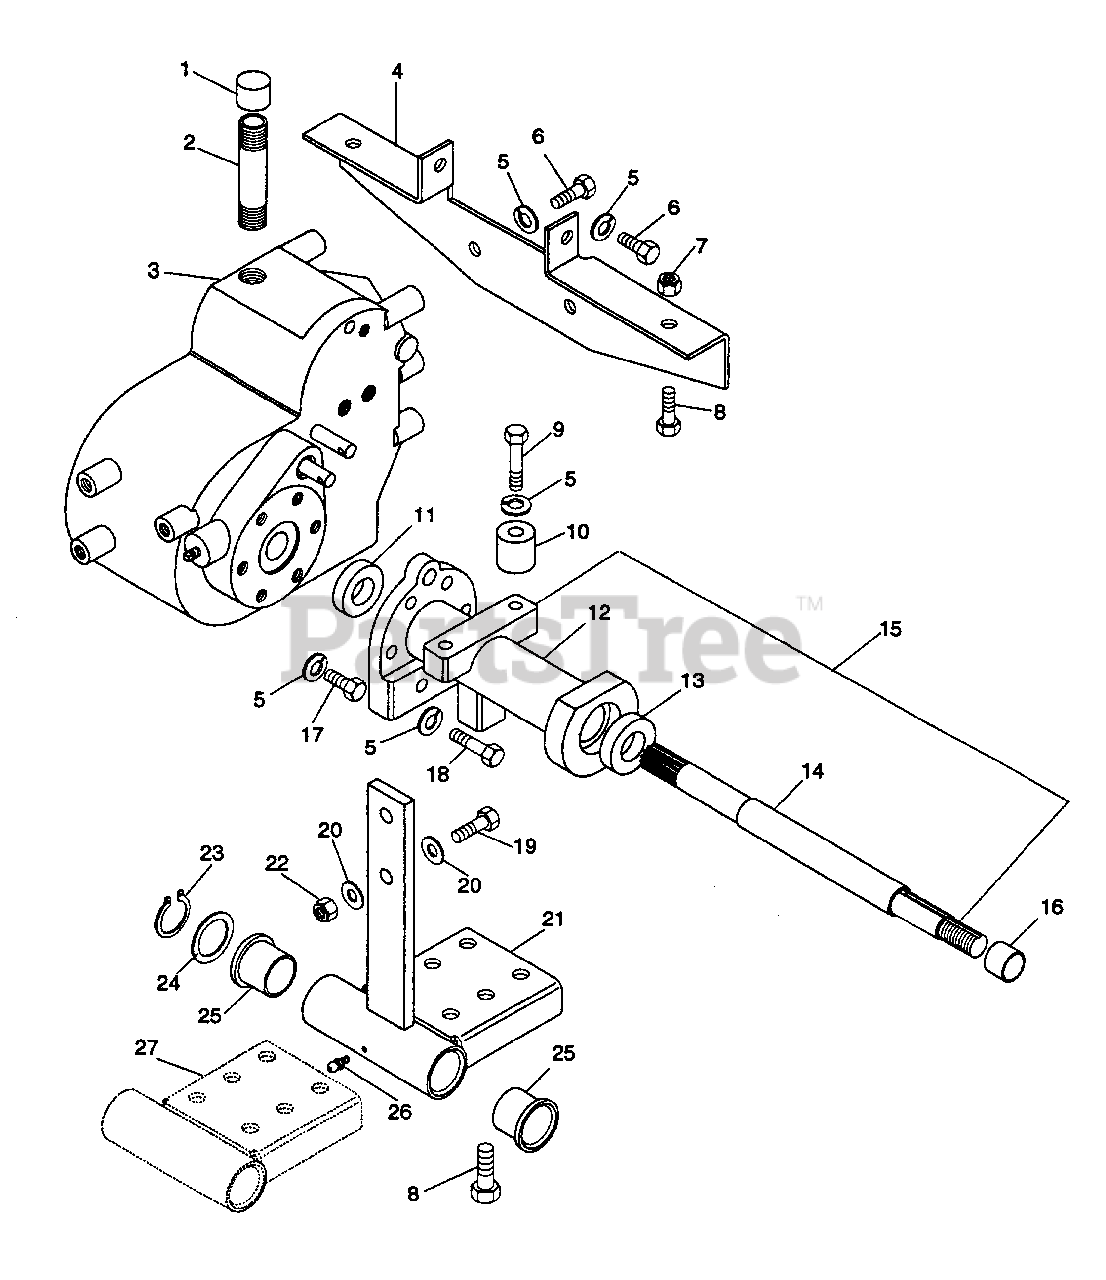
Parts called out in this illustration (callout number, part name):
1	CAP, PIPE .75 UNFIN MAL LR
2	NIPPLE, PIPE .75 X 5.0 UNFIN STL
3	TRANSAXLE
4	PLT, TRANSAXLE
5	WSHR-LOCK .50 REG.
6	BLT-HEX .50-13 X 1.25 PL GR 5
7	NUT-LK-NYL .625-11 PL
8	BLT-HEX .625-11 X 1.50
9	BLT-HEX .50-13 X 2.75 PL GR 5
10	SPCR, FRAME
11	RING, ALIGNMENT
12	HOUSING, AXLE
13	BRG, BALL 1.18 X 2.440 X .629
14	AXLE
15	ASM, AXLE HOUSING
16	SPCR, AXLE 1.75 X .800 ST
17	BLT-HEX .50-13 X 1.50 PL GR 5
18	BLT-HEX .50-13 X 2.25 PL GR 5
19	BLT-HEX .50-13 X 1.75
20	WSHR-FL-STL .531 X 1.062 X .095
21	WLDMT, PIVOT BRKT
22	NUT-LK-NYL .50-13 PL
23	RING, RETAINING
24	WSHR-THRST 1.50 X 2.18 X .063
25	BSHG-FLG 1.154 X 1.756 X 1.688 X 2.2
26	FTG., LUBE; .25-28 SELF-THREAD
27	WLDMT, PIVOT BRACKET
